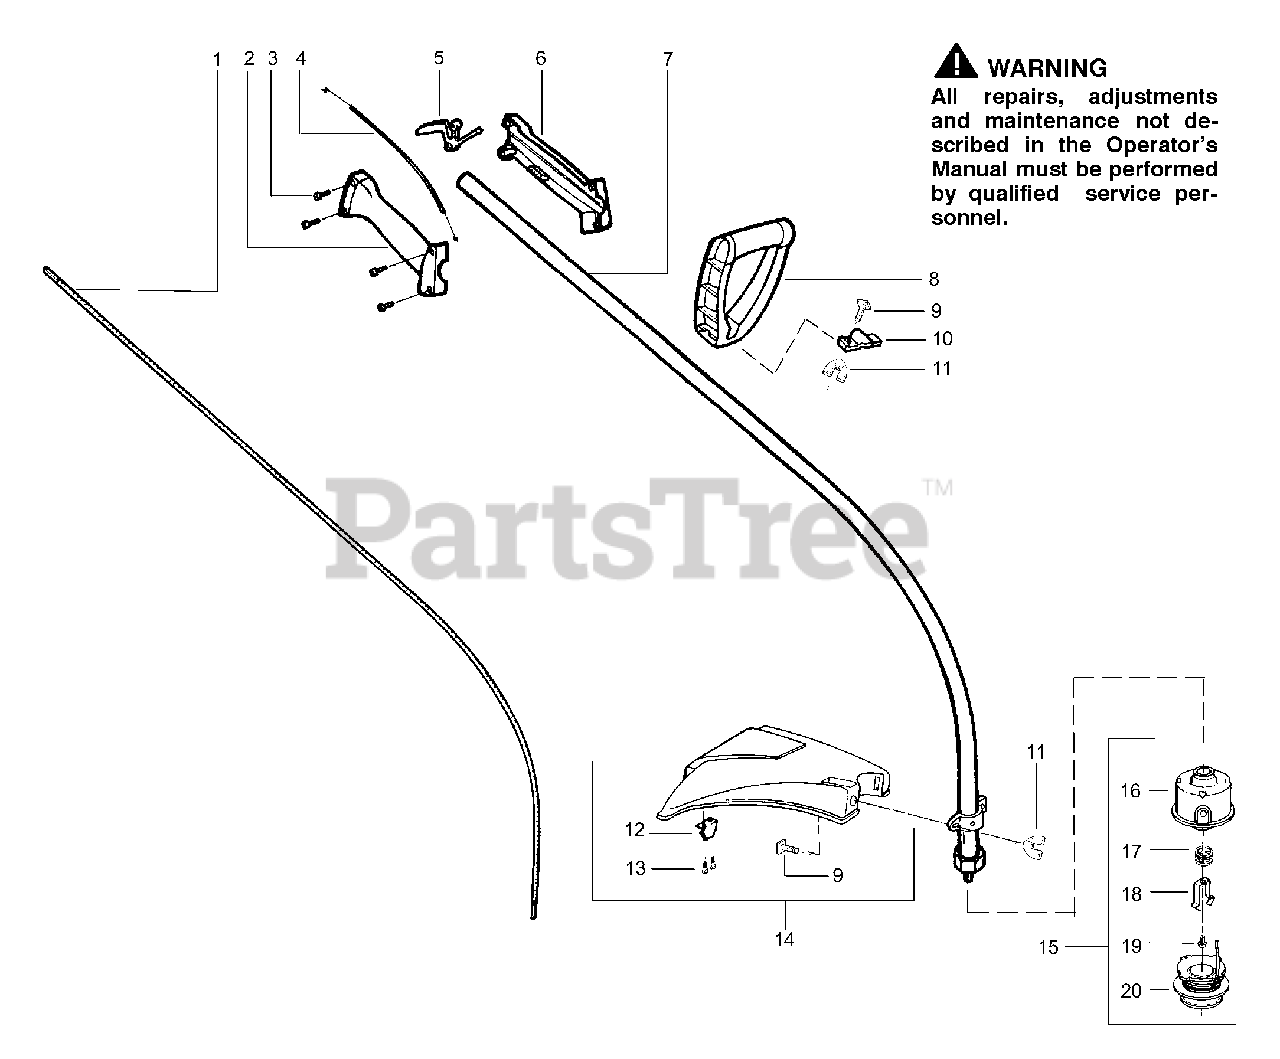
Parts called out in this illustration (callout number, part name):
1	Shaft-Flex
2	Throttle Hsg. (Right)
3	Screw-Throttle Hsg.
4	Kit-Throttle Cable Ass'y.
6	Throttle Hsg. (Left)
7	Drive Shaft Hsg. Ass'y
8	Assist Handle
9	Bolt-Handle/Shield
10	Clamp-Handle Assist
11	Wingnut-Handle/Shield
12	Line Limiter
13	Screw-Line Limiter
14	Kit-Shield Ass'y.
15	Cutting Head Ass'y.
16	Kit-Hub Ass'y
17	Spring-Compression
18	Clip-Retainer-Head
19	Screw w/ Washer-Head
20	Spool w/Line
